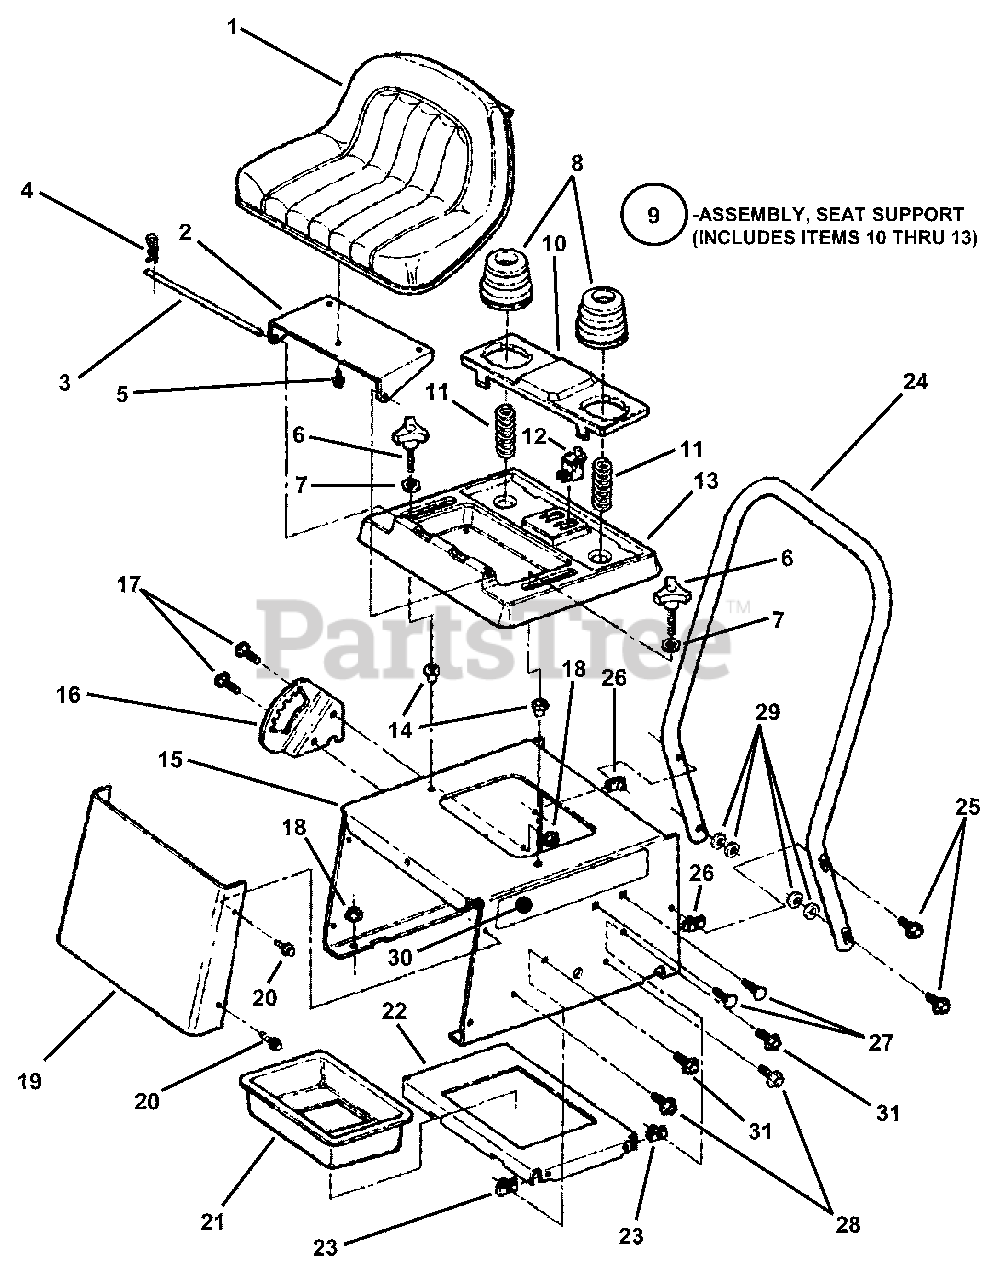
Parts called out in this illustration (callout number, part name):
1	SEAT
2	BRACKET, Seat Support
3	ROD, Seat Hinge
4	PIN, 3/32 x 1-1/2" Hair
5	BOLT, 5/16-18 x 1/2" Hex Flange Lock, Grade 5
6	KNOB, Seat Adjustment
7	WASHER, .344 I.D. x 11/16 O.D. x 1/16" Thick Flat
8	RUBBER COVER, Spring
9	ASSEMBLY, Seat Support
10	HOLDER, Seat Cushion
11	SPRING, Cushion Holder
12	SWITCH, Seat (NC)
13	SUPPORT, Seat
14	RIV-NUT, 5/16-18 Round
15	PEDESTAL, Seat
16	QUADRANT, Height-of-Cut
17	BOLT, 5/16-18 x 3/4" Short Neck Carriage, Grade 5
18	NUT, 5/16-18 Hex Flange Lock, Grade 5
19	COVER, Seat Pedestal Front
20	SCREW, #10-24 x 1/2" Hex Washer Self-Tap (Torx)
21	TRAY, Battery
22	PLATE, Battery Holder
23	U-NUT, 1/4-20
24	HANDLE, Grab
25	SCREW, 5/16-18 x 1-3/4" Hex Washer Self-Tap
26	NUT, 5/16 Push-On
27	BOLT, 1/4-20 x 3/4" Short Neck Carriage, Grade 5
28	BOLT, 1/4-20 x 3/4" Hex Flange Lock, Grade 5
29	WASHER, 5/16" I.D. x 1" O.D. x 3/32" Thick Flat
30	DECAL, Seat Pedestal
31	SCREW, 1/4-20 x 5/8 Truss Head Torx
